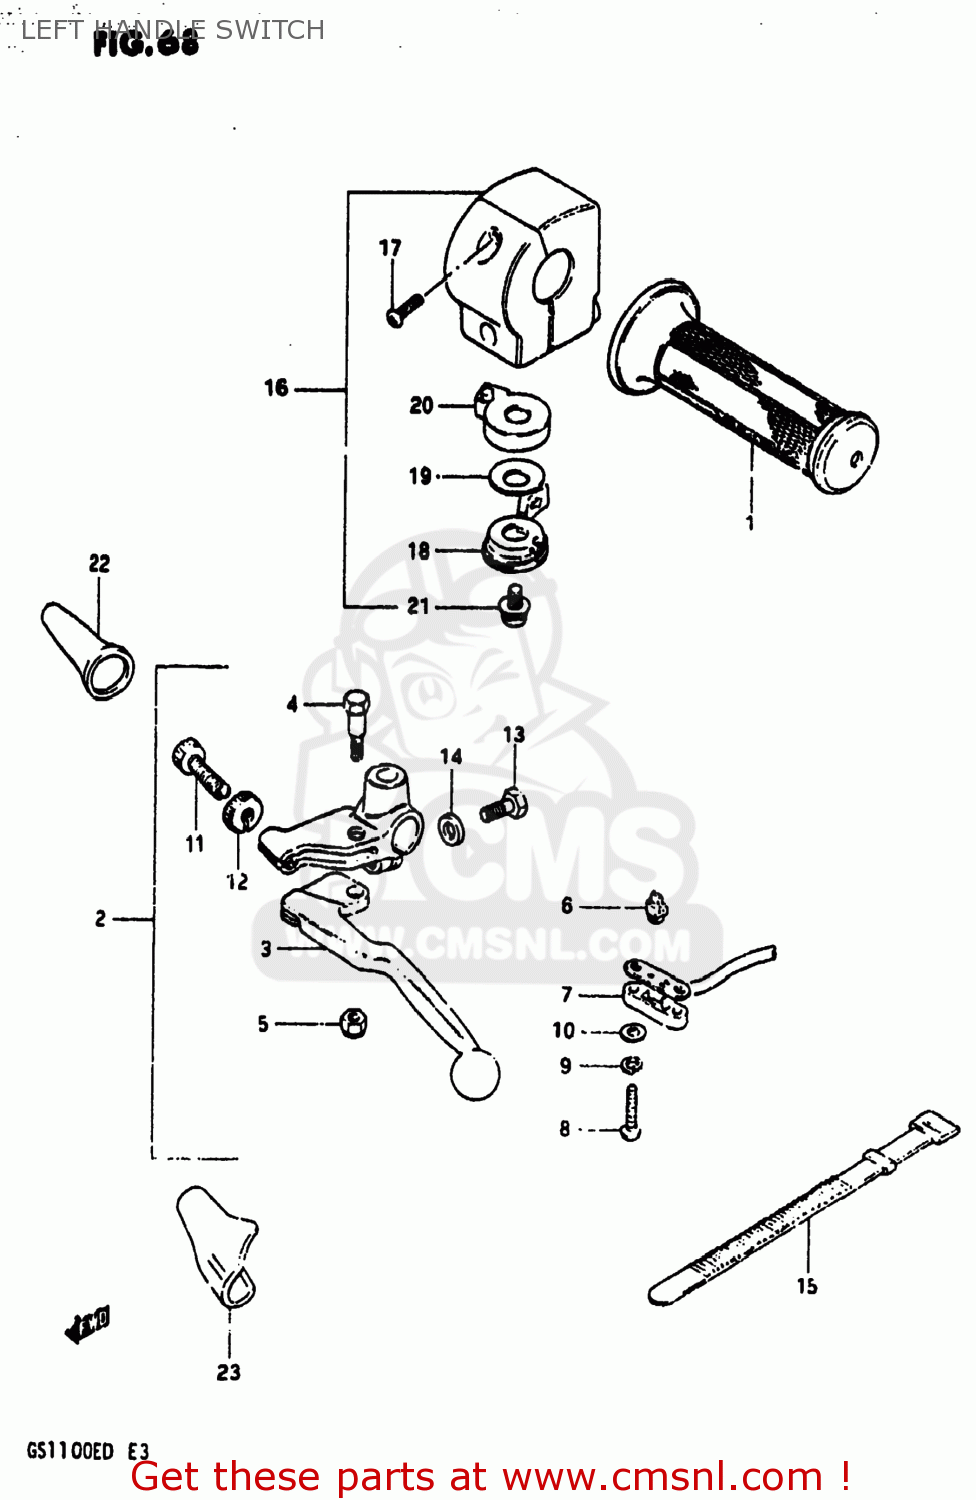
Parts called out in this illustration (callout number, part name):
1	GRIP,L
2	LEVER ASSEMBLY
3	LEVER,CLUTCH
4	BOLT,LEVER
5	NUT 6MM
6	CONTACT,SWITCH
7	COVER,FR BK TERMINAL BASE
8	SCREW
9	LOCK WASHER
10	WASHER
11	ADJUSTER,CABLE
12	NUT,CABLE ADJUSTER
13	BOLT,CLUTCH LEVER HOLDER
14	SPACER
15	CLAMP(L:120)
16	SWITCH ASSEMBLY,HANDLE,LEFT
17	SCREW
18	LEVER,STARTER
19	WASHER,ADJUSTER
20	BODY,CHOCK
21	SCREW,CHOKE LE
22	BOOT,CLUTCH CABLE
23	COVER,CLUTCH LEVER
24	BUTTON,STARTER
25	SPRING,STARTER BUTTON
26	CONTACT,STARTER BUTTON
